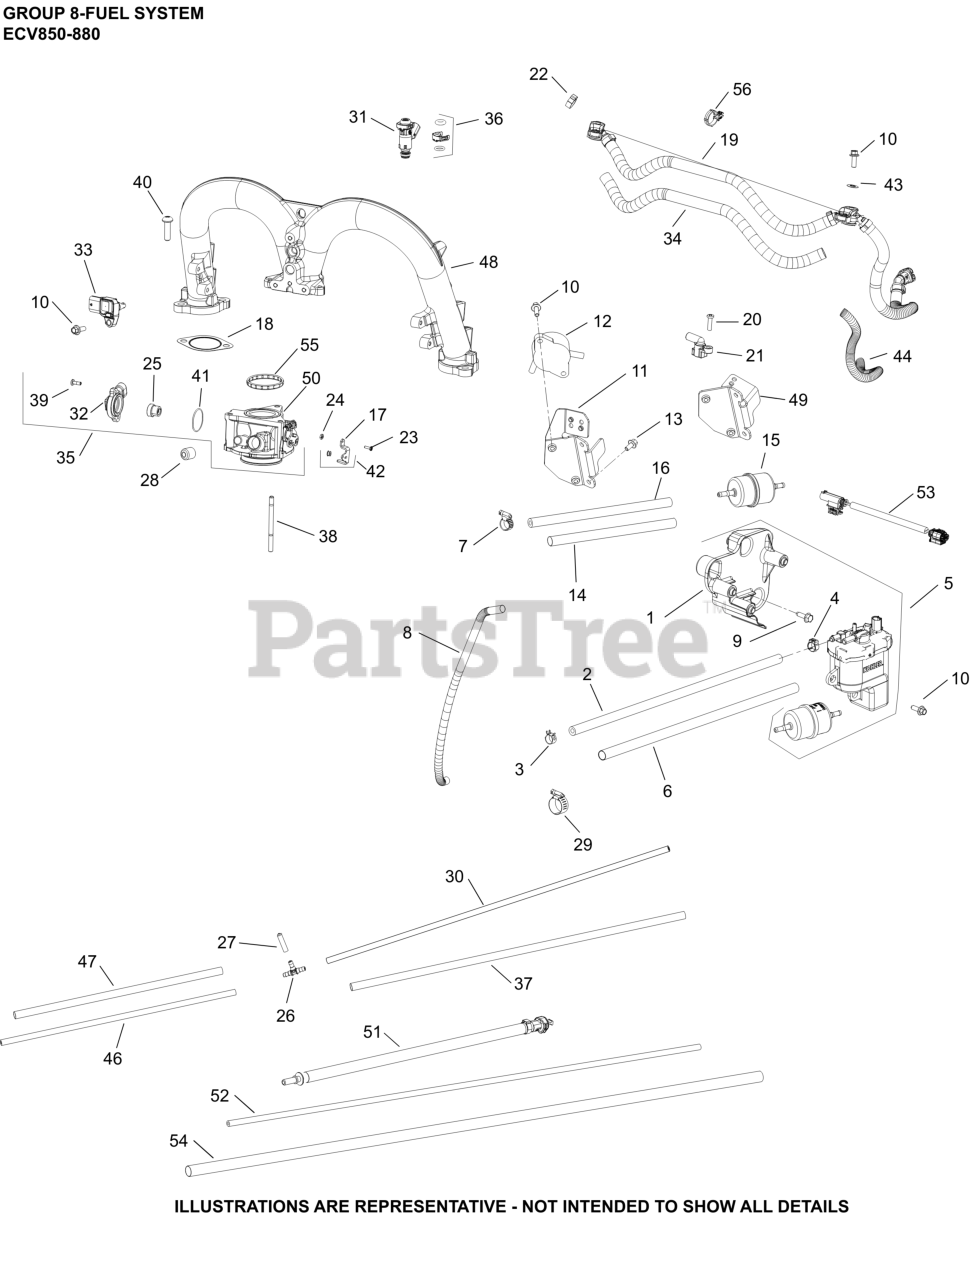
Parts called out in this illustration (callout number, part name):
1	BAFFLE, FUEL PUMP
3	SPRING CLAMP, HOSE
4	CLAMP, OETIKER
5	KIT, FUEL PUMP MODULE
7	CLAMP, HOSE (KM)-USE 25 237 31-S
8	SLEEVE, ANTI-ABRASION
9	SCREW, THREAD FORMING
10	SCREW, FLG M6X1.0X16
11	BRACKET, PULSE PUMP
12	PUMP, FUEL
13	SCREW, FLG M6X1.0X12
15	FILTER, FUEL
16	HOSE,LW PERM.FUEL 24.00"-USE 25 111 81-S
18	GASKET, INTAKE MANIFOLD
19	RAIL, FUEL - ASSEMBLY (ECV850-880)
22	CLAMP, HOSE
25	MAGNET ASSEMBLY, TPS
26	TEE CONNECTOR
27	CAP, MASKING
28	CAP, MASKING
31	INJECTOR, FUEL
32	SENSOR, THROTTLE POSITION
33	SENSOR, T-MAP
34	SLEEVE, ANTI ABRASION
36	KIT, FUEL INJECTOR O-RING
37	SLEEVE, ANTI ABRASION
38	STUD,M6X1.0X84
40	SCREW, M8 x 30 PAN HD, TORX DRIVE
41	O-RING, TPS SENSOR
43	CLIP, RETAINER
44	SLEEVE, ANTI ABRASION
48	MANIFOLD, INTAKE EFI
55	O-RING, THROTTLE BODY
56	RETAINER, WIRE HARNESS
